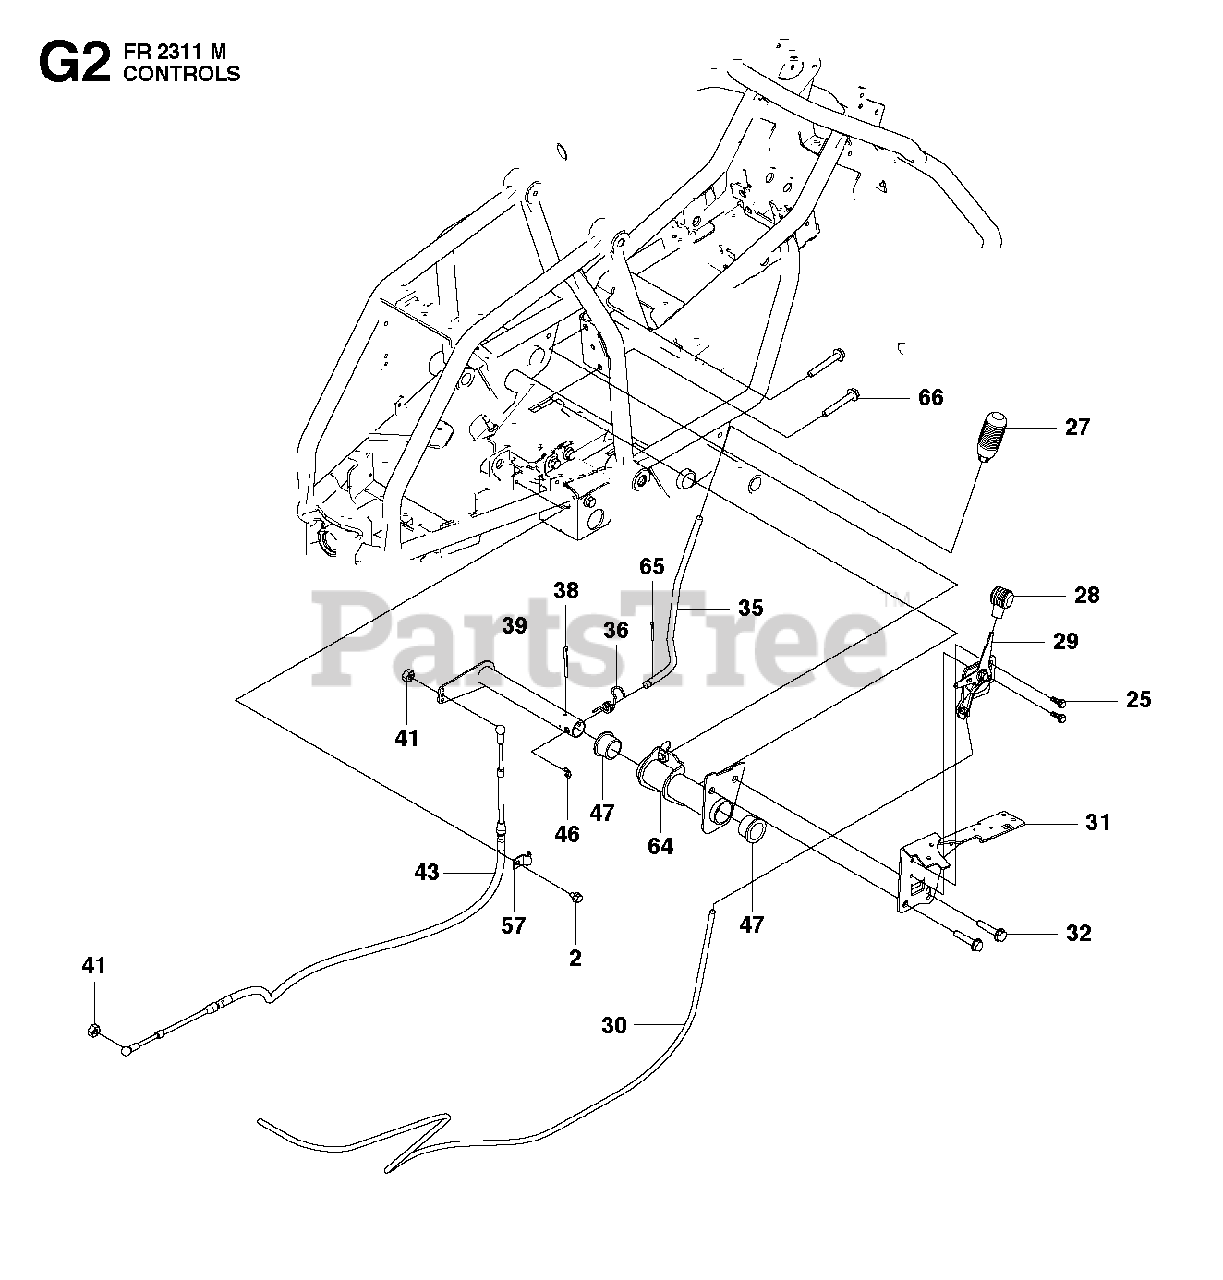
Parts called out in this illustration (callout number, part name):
38	SPLIT PIN
41	LOCKNUT M5
46	RETAINING RING
47	BUSH
65	COTTER PIN
